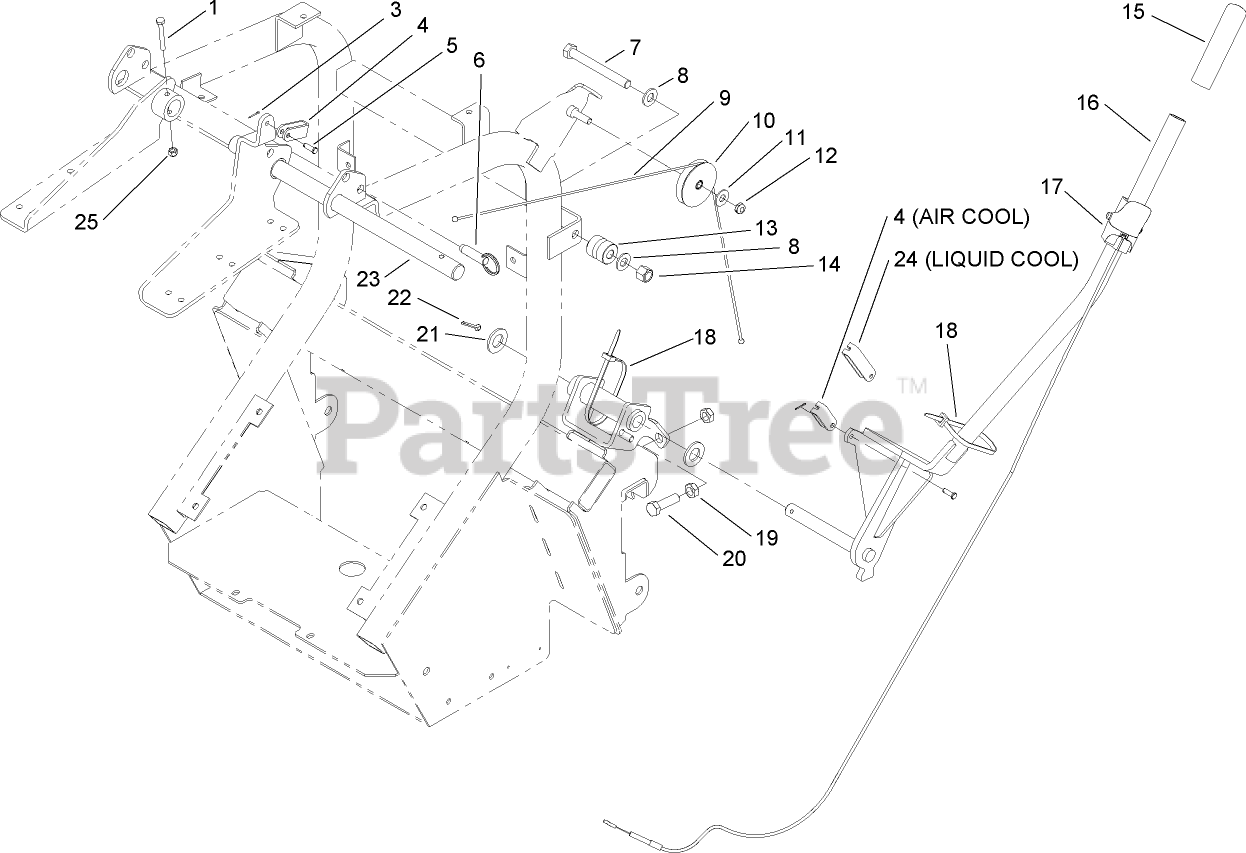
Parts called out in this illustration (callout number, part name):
1	SCREW-HH
3	PIN-COTTER
4	CLEVIS-SHORT
5	PIN-CLEVIS
6	PIN-RELEASE, QUICK
7	SCREW-HH
8	WASHER-FLAT
9	CABLE-DOOR
10	PULLEY ASM
11	WASHER-FLAT
12	NUT-LOCK, NI
13	ROLLER-CABLE
14	NUT-LOCK, NI
15	GRIP-FOAM
16	DUMP ARM ASM
17	LATCH-CABLE, DUMP
18	TIE-CABLE
19	NUT-JAM
20	SCREW-HH
21	WASHER-FLAT
22	PIN-COTTER
23	SHAFT-HINGE
24	CLEVIS-LONG
25	NUT-LOCK, NI
